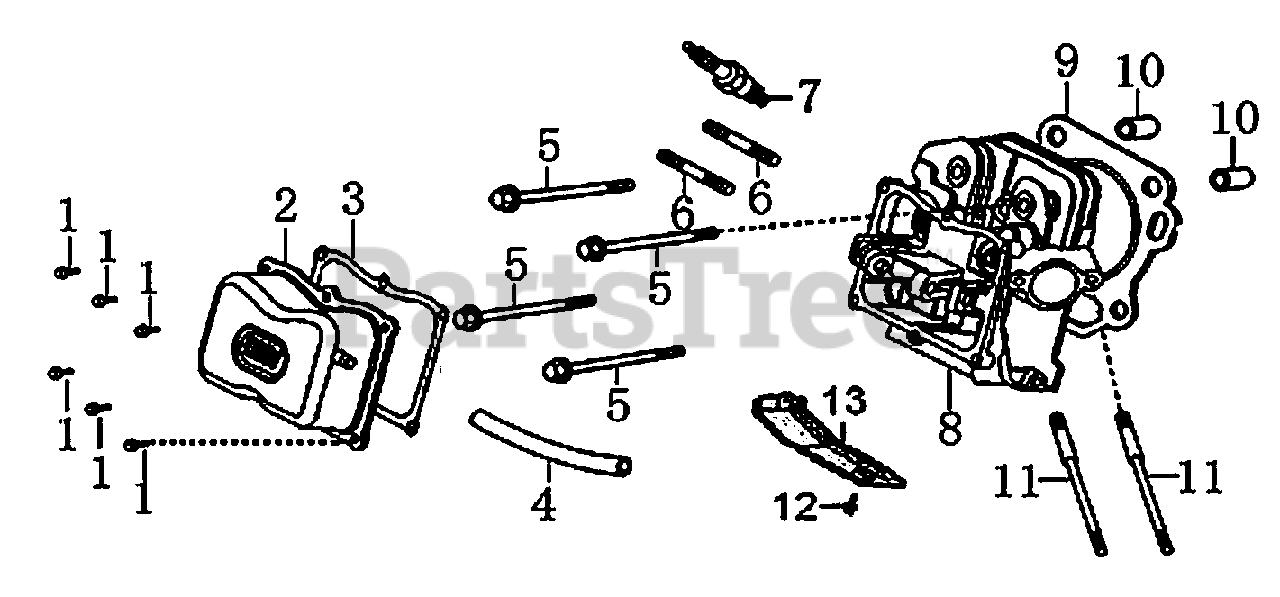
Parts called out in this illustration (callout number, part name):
1	BOLT, FLANGE
2	COVER COMP. HEAD
3	GASKET, VALVE COVER
4	TUBE, BREATHER
5	BOLT, FLANGE, 10×80
6	BOLT, STUD, EXHAUST
7	SPARK PLUG
8	CYLINDER HEAD COMP
9	GASKET, CYLINDER
10	PIN, DOWEL
11	BOLT, STUD, INTAKE
12	BOLT, FLANGE M6×12
